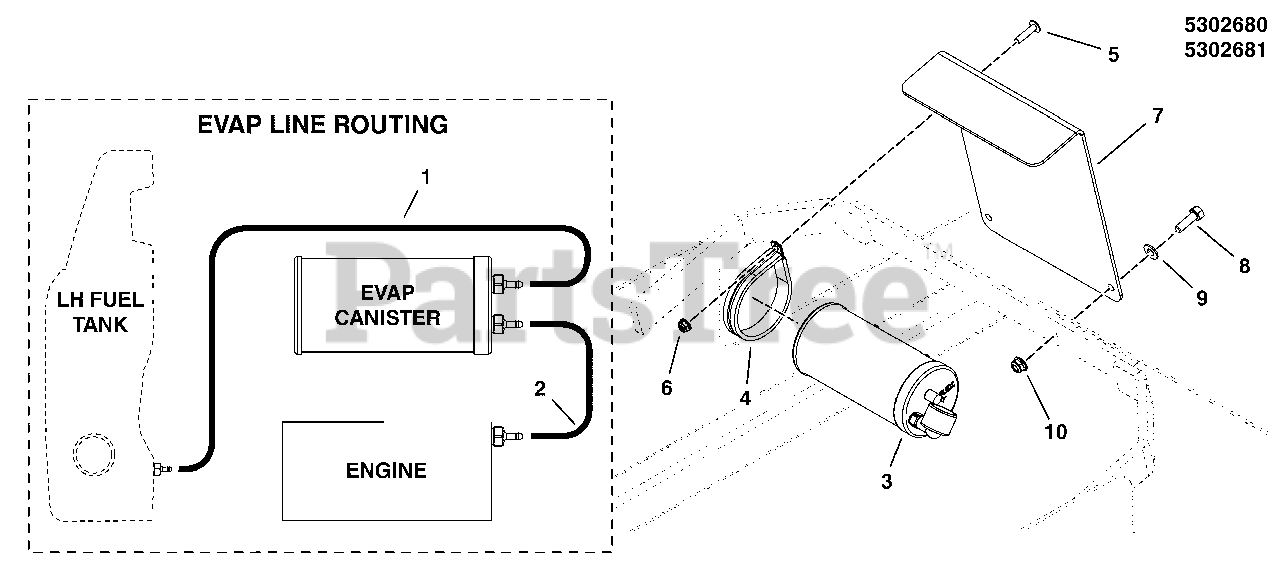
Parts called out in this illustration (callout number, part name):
2	HOSE, VAPOR, 5MM ID, 30.00 LG
3	CNSTR, CARB, 6 GAL
4	CLAMP, 3" ID, CUSHIONED, STAINLESS
5	BOLT, 1/4-20 X 3/4, ALLEN BUTTON HD, YZ
6	NUT, 1/4-20 HEX NYLOCK FLANGE (5025391)
7	PLATE, CARB CANISTER MOUNT - BLK
8	BOLT, 5/16-18 X 1 GD5 YZ
9	WASHER, 5/16 SAE
10	NUT, 5/16-18 HEX NYLOCK FLANGE
11	DECAL, EPA CERT
